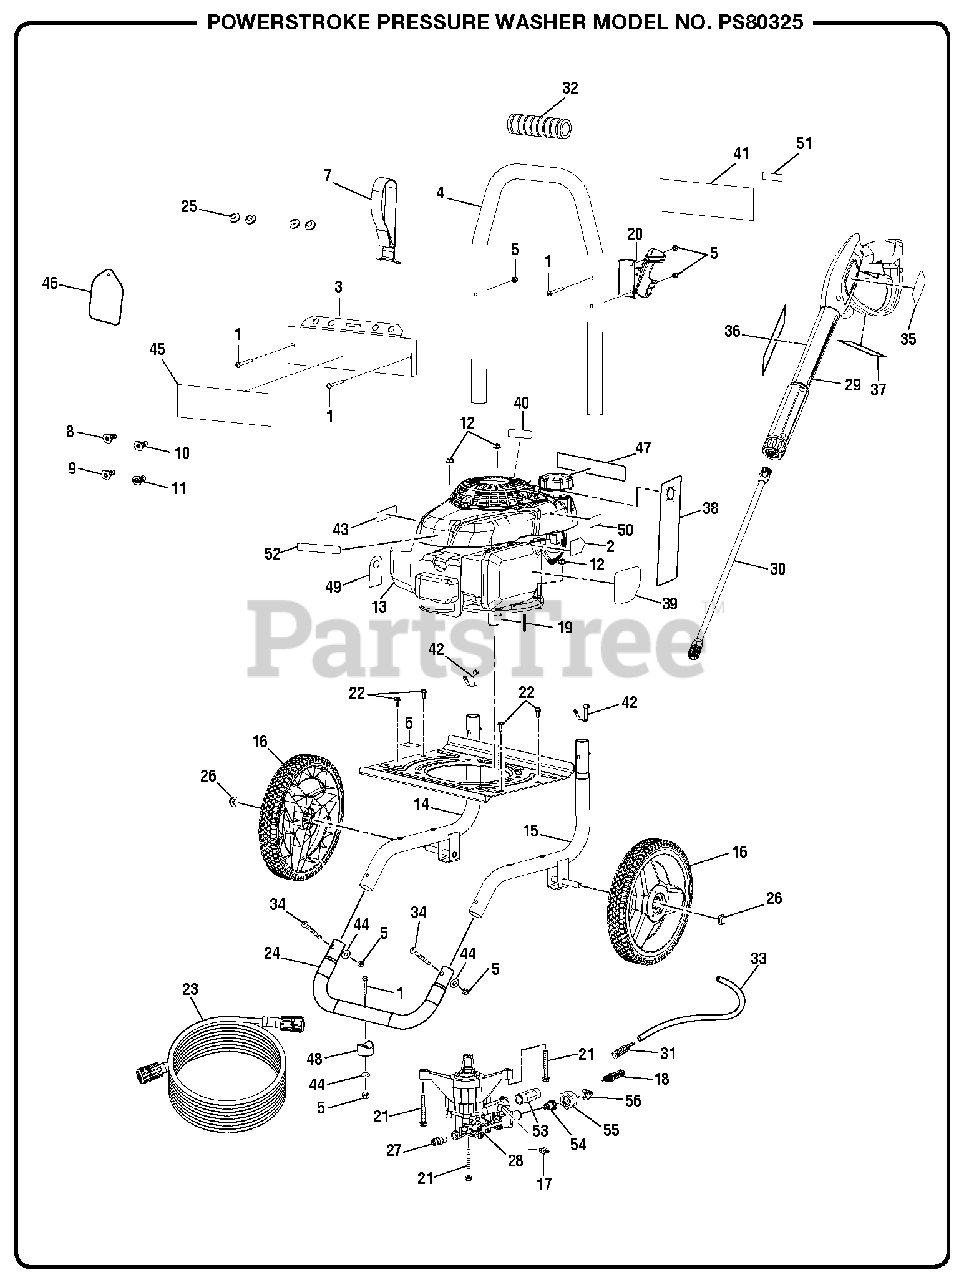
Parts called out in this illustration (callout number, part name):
1	Screw (M6 x 48 mm, T30 Torx Pan Hd)
2	Engine On/Off Label
3	Hose and Nozzle Holder
5	Lock Nut (M6 x 1)
6	Oil Fill Location Label
7	Hose Holder Strap
8	40 deg Nozzle
9	Soap Nozzle
10	25 deg Nozzle
11	0 deg Nozzle
12	Flange Lock Nut (M8 x 1.25)
13	Engine (Honda GCV 190, 190cc OHC Vertical)
14	Main Frame Assembly
15	Main Frame Assembly
17	Detergent Suction Kit
18	Pump Unloader Valve
19	Output Shaft Key
20	Wand Holder
21	Flange Bolt (M8 x 60 mm, Hex Hd)
22	Flange Bolt (M6 x 16 mm, Hex Hd)
23	Hose (25 ft.)
24	Front Frame
26	Push Cap Nut
27	Thermal Release Valve
28	Pump
29	Trigger Handle Assembly
30	Extension Wand
31	Chemical Siphon Filter
32	Foam Grip
33	Chemical Siphon Tube
34	Screw (M6 x 42 mm, T30 Tox Pan Hd)
35	Trigger Handle Warning Label (Eng)
36	Trigger Handle Warning Label (Fr/Sp)
37	Trigger Handle Rating Label
38	Danger Hangtag
39	Engine Control Label
40	Combustion Label
41	Quick Start Label
42	Lock Button w/Spring Clip
43	Hot Surface Label
44	Washer (1/4 in)
45	Performance Label
46	Nozzle Hangtag
47	Danger Label
49	Dipstick Hangtag
50	No E85 Label
51	Inquiries Label
52	Honda Brand Label
53	Outlet Tube
56	Filter Screen (Pump Inlet)
